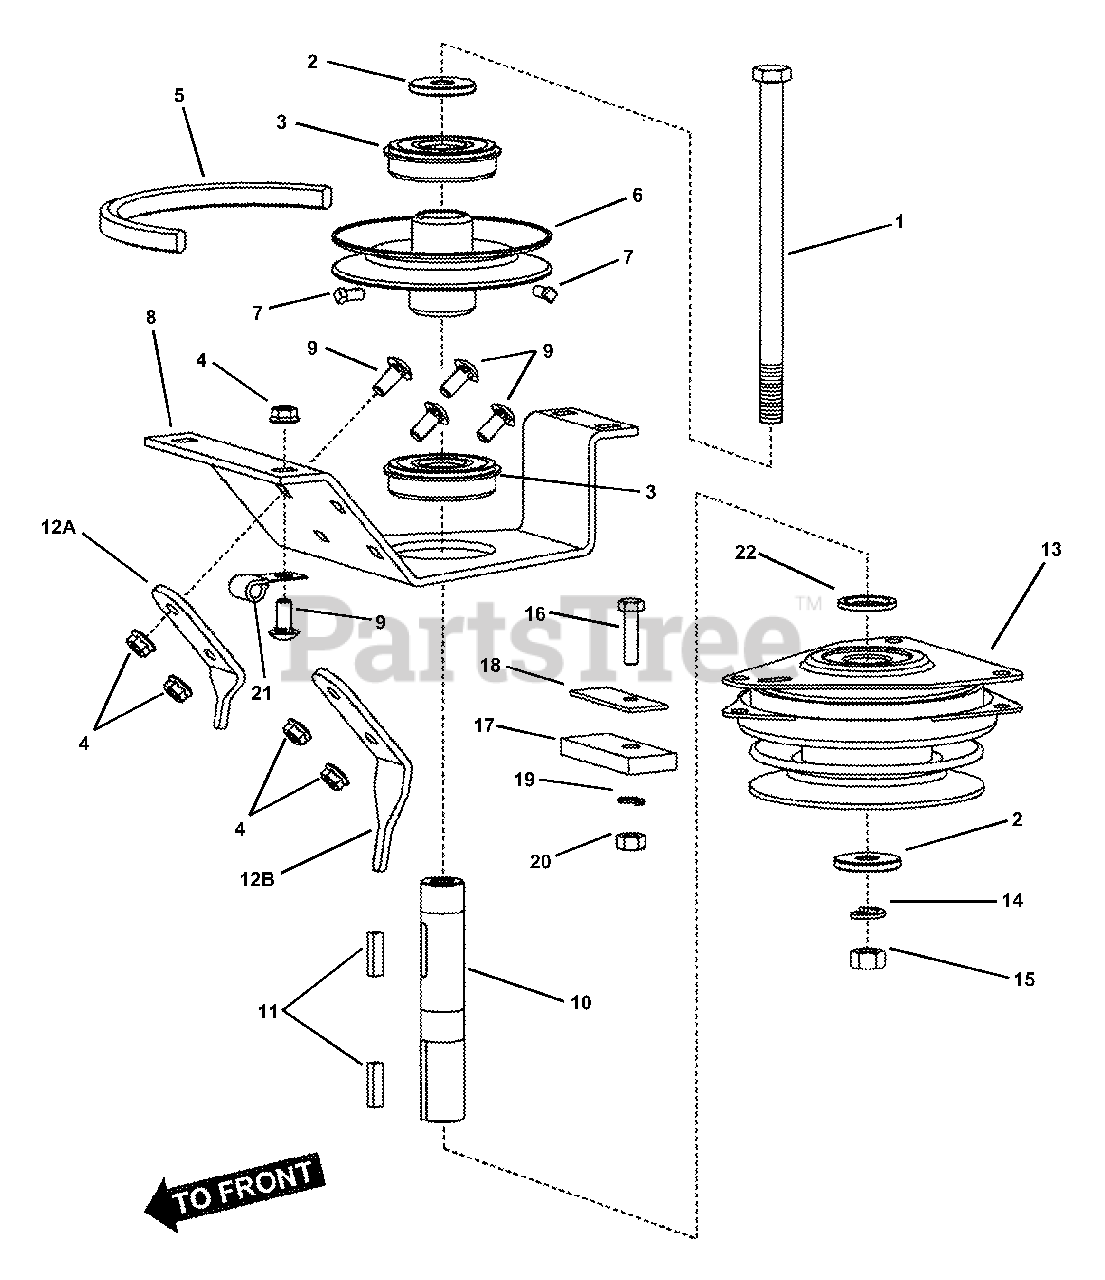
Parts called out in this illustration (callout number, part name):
1	SCREW, 7/16-20 x 8" Hex Head Cap, Grade 5
2	WASHER, 7/16 x 1" O.D. Flat
3	BEARING, 6305 w/Snap-Ring
4	NUT, 5/16-18, Grade 5
5	V-BELT, Drive 5L Cogged (50.170" nom. effective length)
6	PULLEY, Jackshaft
7	SCREW, 1/4-20 x 1/2" Set w/Patch
8	SUPPORT, Jackshaft
9	BOLT, 5/16-18 x 3/4 Carriage, Grade 5
10	JACKSHAFT
11	KEY, 1/4 x 1" Square (Qty. 1 on 38" units)
12A	BRACKET, Anti-Rotate (33" units & 2001 38" units)
12B	BRACKET, Anti-Rotate (YZ13381BE & YZ145382BVE 1999 units)
13	CLUTCH, Electric (Ogura) (33" units)
14	WASHER, 7/16" Split Lock
15	NUT, 7/16-20, Grade B
16	SCREW, 5/16-18 x 1-1/4", Hex Head Cap, Grade 5
17	BUMPER, Electric Clutch
18	WASHER, Rectangular Steel
19	WASHER, 5/16" Split Lock
20	NUT, 5/16-18, Grade 5
21	CLIP, Wire, 7/16
22	WASHER (33" units & 2001 38" units)
